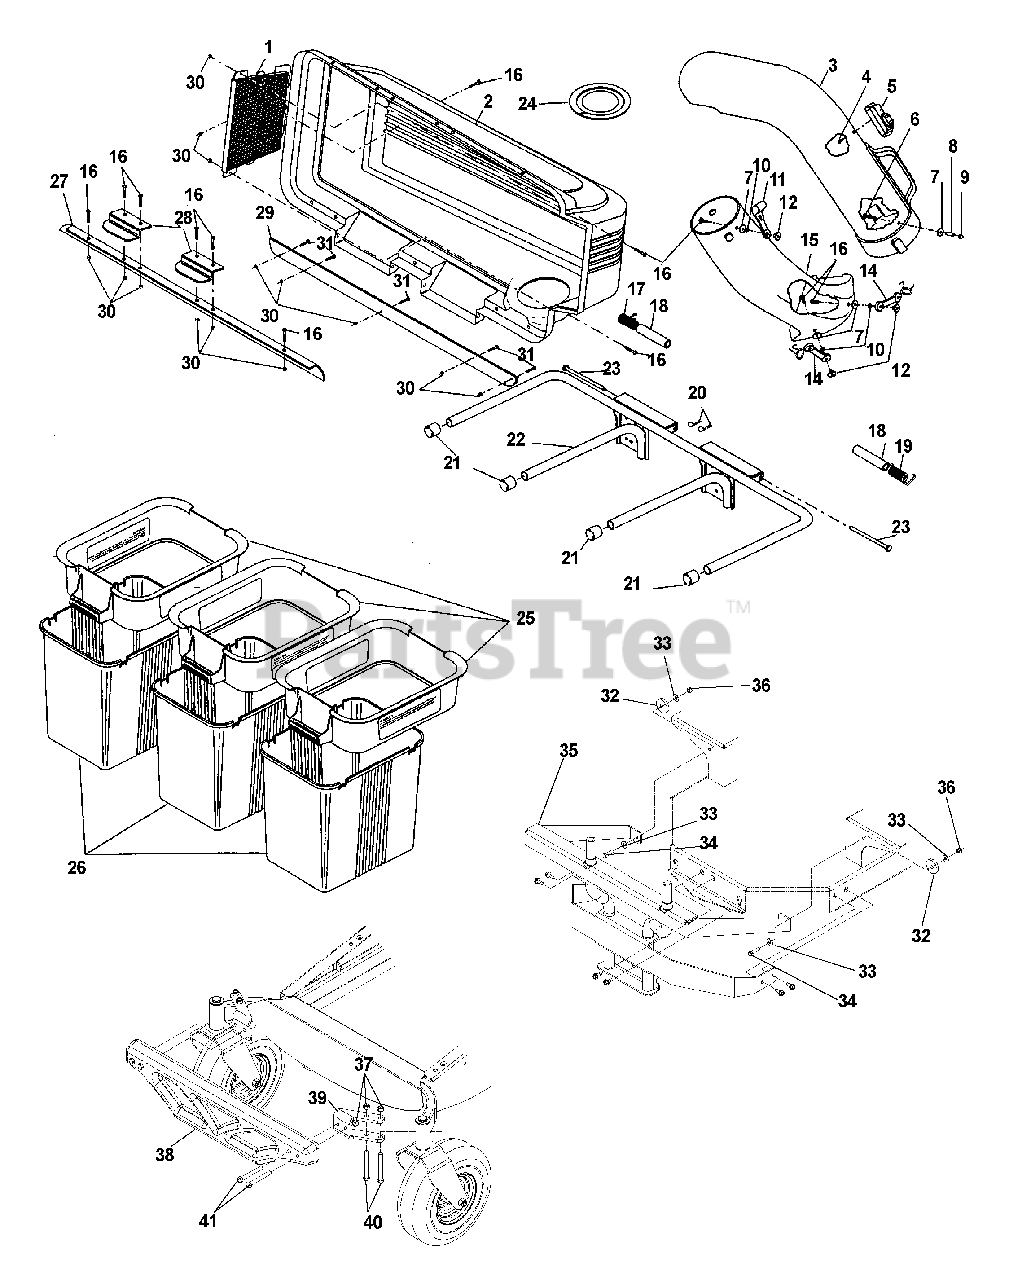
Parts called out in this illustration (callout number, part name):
1	Screen, cover
2	Cover
3	Chute, upper
4	Screw, #10-14 x 1/2, special
5	Dump bag indicator
6	Screw, #10-24 x 1 1/8
7	Washer, 3/16 x 3/4 x 16 Ga.
8	Spacer, split
9	Nut, #10-24, acorn
10	Lockwasher
11	Latch, chute
12	Nut, weld
14	Latch, assembly
15	Chute, lower
16	Screw, #10-24 x 5/8
17	Spring, cover L.H. (black)
18	Spacer, cover
19	Spring, cover R.H. (gray)
20	Spring, retainer
21	Plug, tubing end
22	Bagger, frame
23	Pin, hinge
24	Gasket, cover
25	Container, top
26	Container, bottom
27	Seal, cover
28	Handle, bagger cover
29	Strip, reinforcement
30	Nut, #10-24, crownlock
31	Screw, #10-24 x 1/2
32	Washer, special
33	Washer, 5/16
34	Bolt, 5/16-18 x 1 1/4
36	Nut, 5/16-18, nyloc
37	Nut, 3/8-16, nyloc
38	Cast weight
39	Weight bracket
40	Bolt, 3/8-16 x 3 1/4
41	Bolt, 3/8-16 x 3
